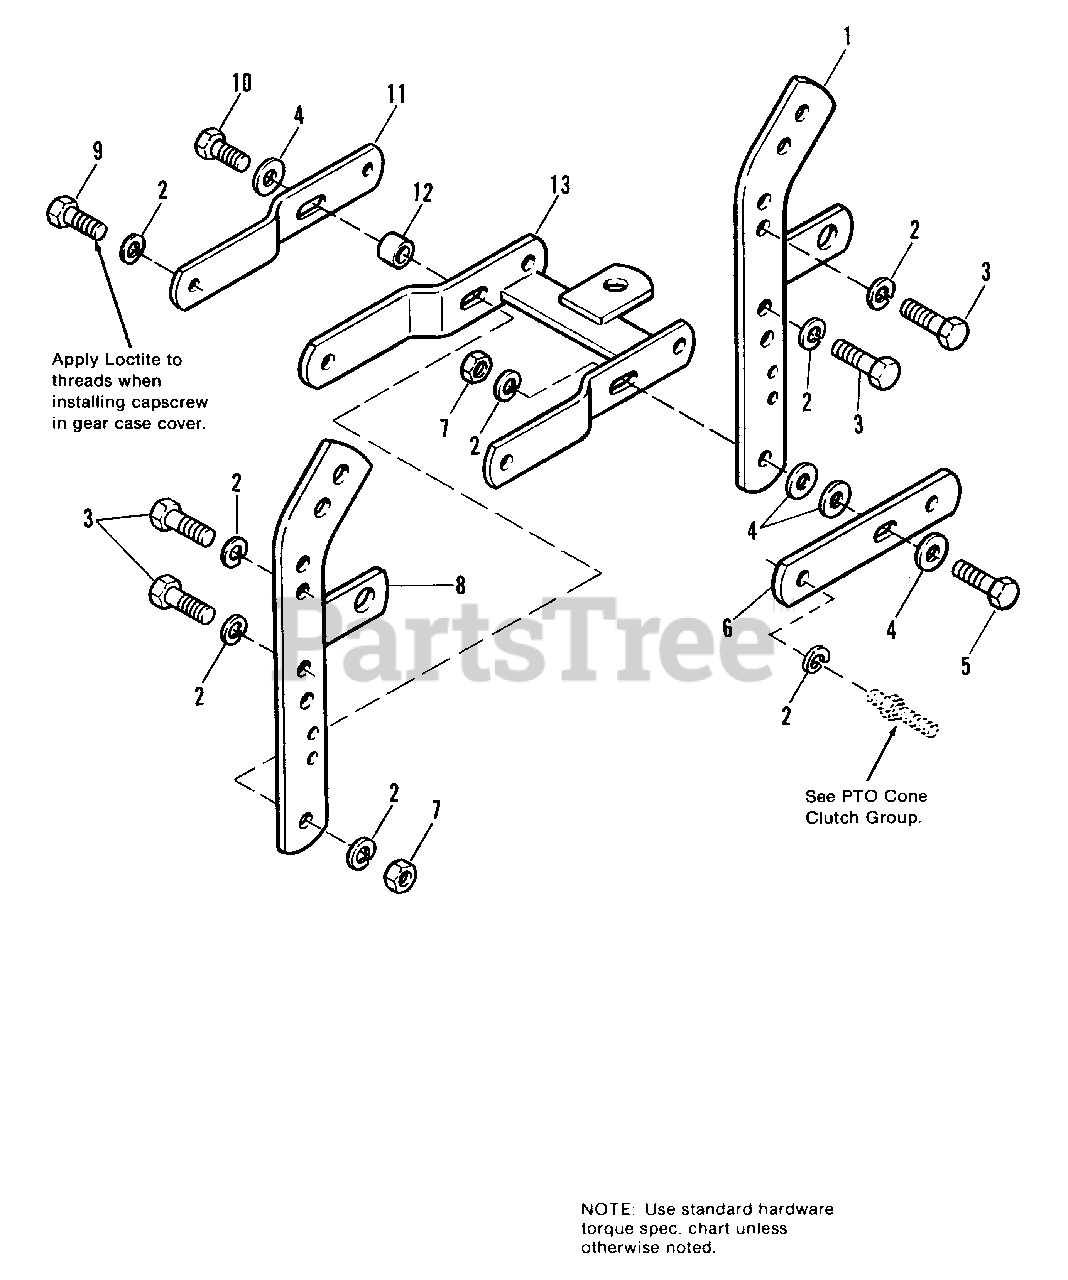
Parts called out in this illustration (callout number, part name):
1	ARM ASSY., L.H.
2	LOCKWASHER, 7/16
3	CAPSCREW, Hex Hd., 7/16-14 x 1
4	WASHER, Plain, 7/16
5	CAPSCREW, Hex Hd., 7/16-14 x 1-1/4
6	BAR, Pull, L.H.
7	NUT, Hex, Full, 7/16-14
8	ARM ASSY., R.H.
9	CAPSCREW, Hex Hd., 7/16-14 x 1-3/4
10	CAPSCREW, Hex Hd., 7/16-14 x 2-1/4
11	BAR, Draw, R.H.
13	DRAW BAR ASSY.
